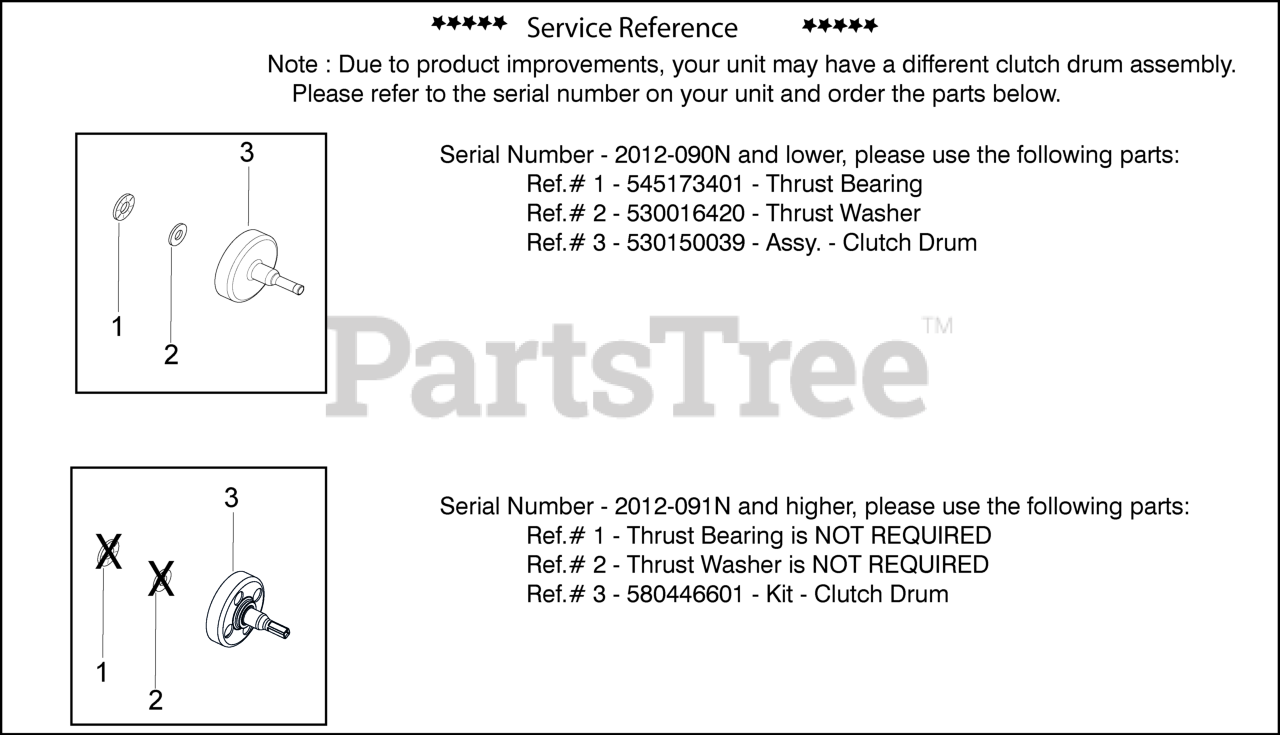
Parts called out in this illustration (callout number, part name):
1	BEARING THRUST
2	WASHER THRUST
3	ASSY-CLUTCH DRUM
3	KIT DRUM CLUTCH ASSY
